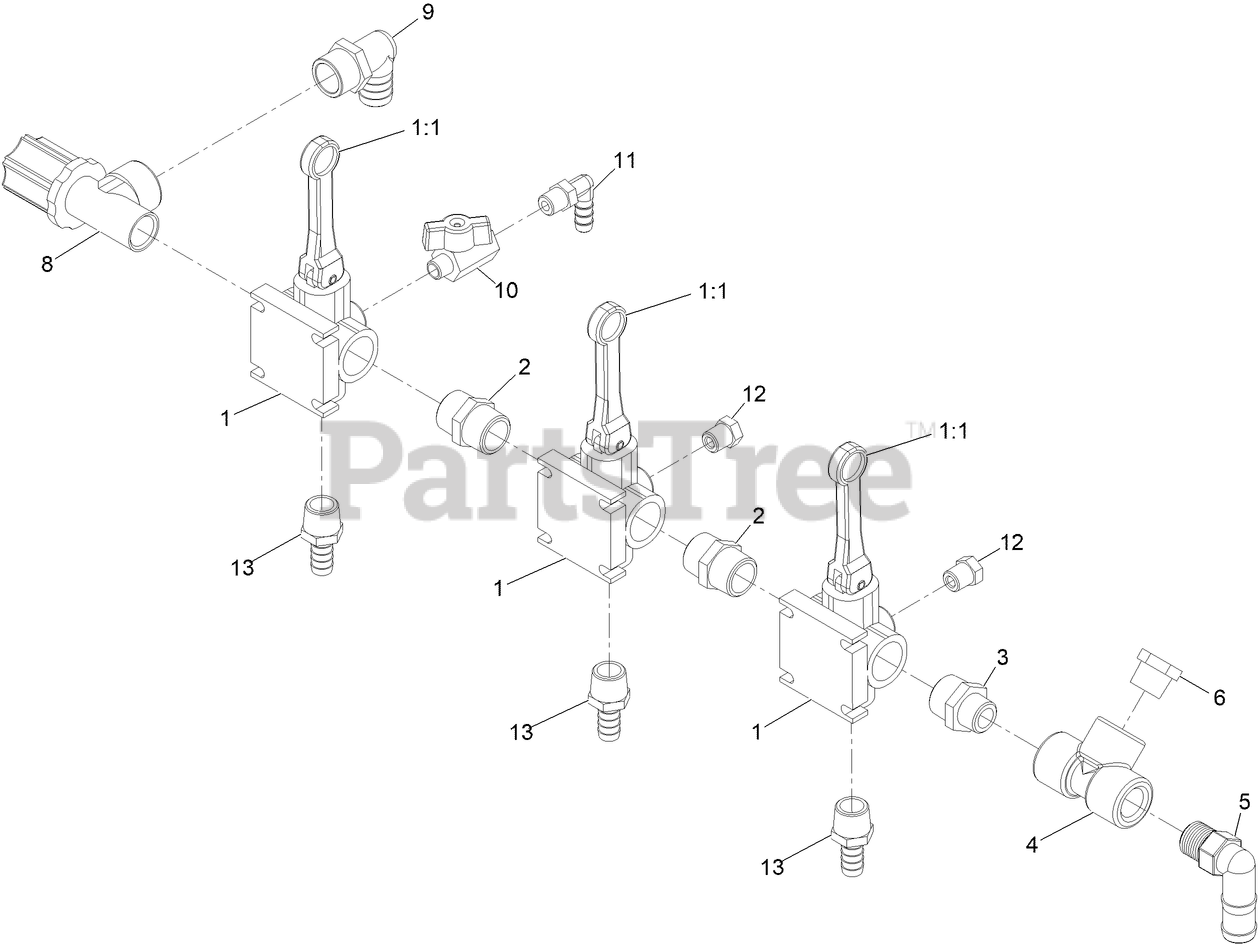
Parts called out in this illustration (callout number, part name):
1	VALVE-DIRECTO
1:1	VALVE HANDLE ONLY AA6B
2	FITTING-NIPPLE
3	FITTING-NIPPLE
5	ELBOW-90
6	FITTING-REDUCER
8	VALVE-THROTTLE
9	FITTING-ELBOW, 90
10	VALVE-CHROME, 1/4
11	FITTING-ELBOW, 90
12	PLUG-VALVE
13	FITTING-HOSEBARB
